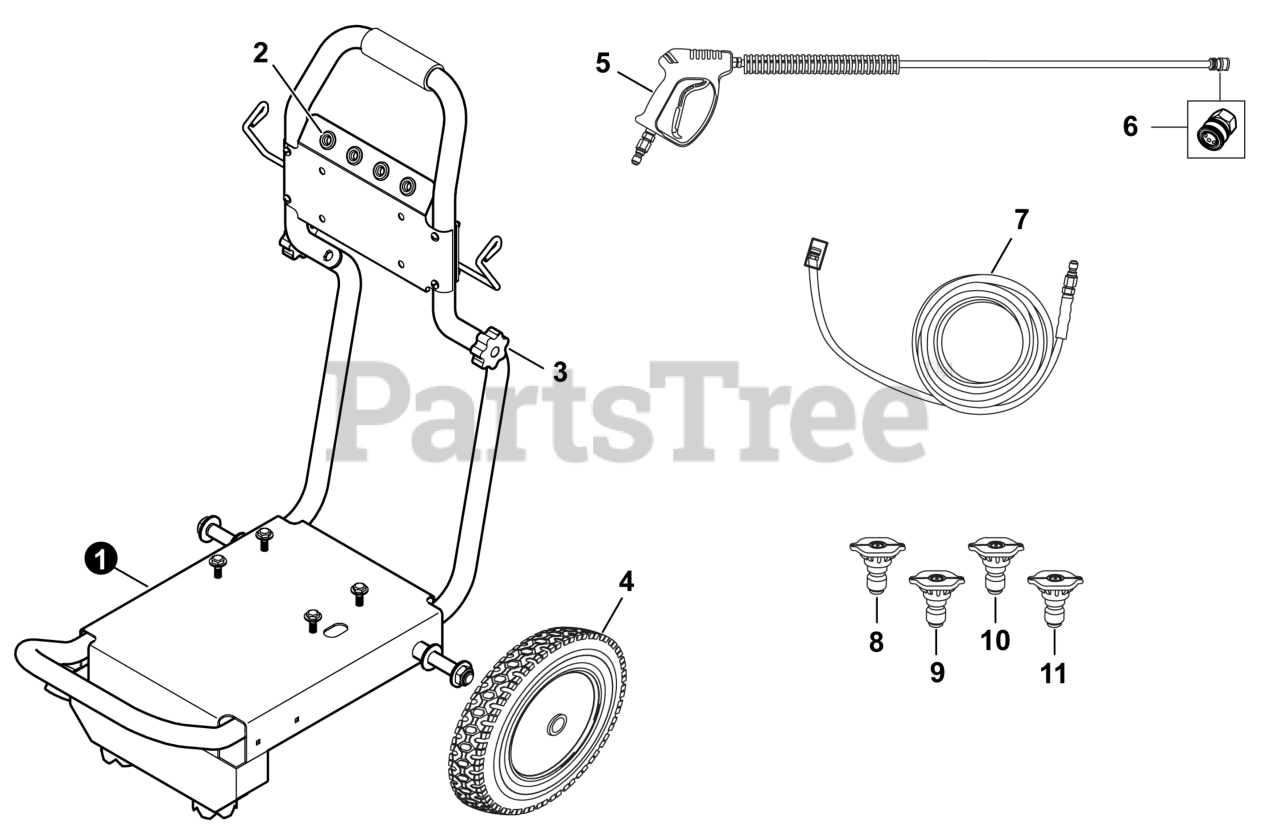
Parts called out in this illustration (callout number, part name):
1	FRAME PW-4200
2	GROMMET, NOZZLE PW-1300 & PW-4200
3	KNOB, HANDLE PW-1300 & PW-4200
4	WHEELS, PW-3100 AND PW-4200
5	GUN & WAND ASSY.
6	FITTING, Q/C 1/4"" FNPT
7	HOSE, 50 ' 4200 PSI
8	LANCE/NOZZLE ASSY., TURBO
9	NOZZLE, #4.0 15 DEGREE
10	NOZZLE, #4.0 40 DEGREE
11	NOZZLE, SOAP
